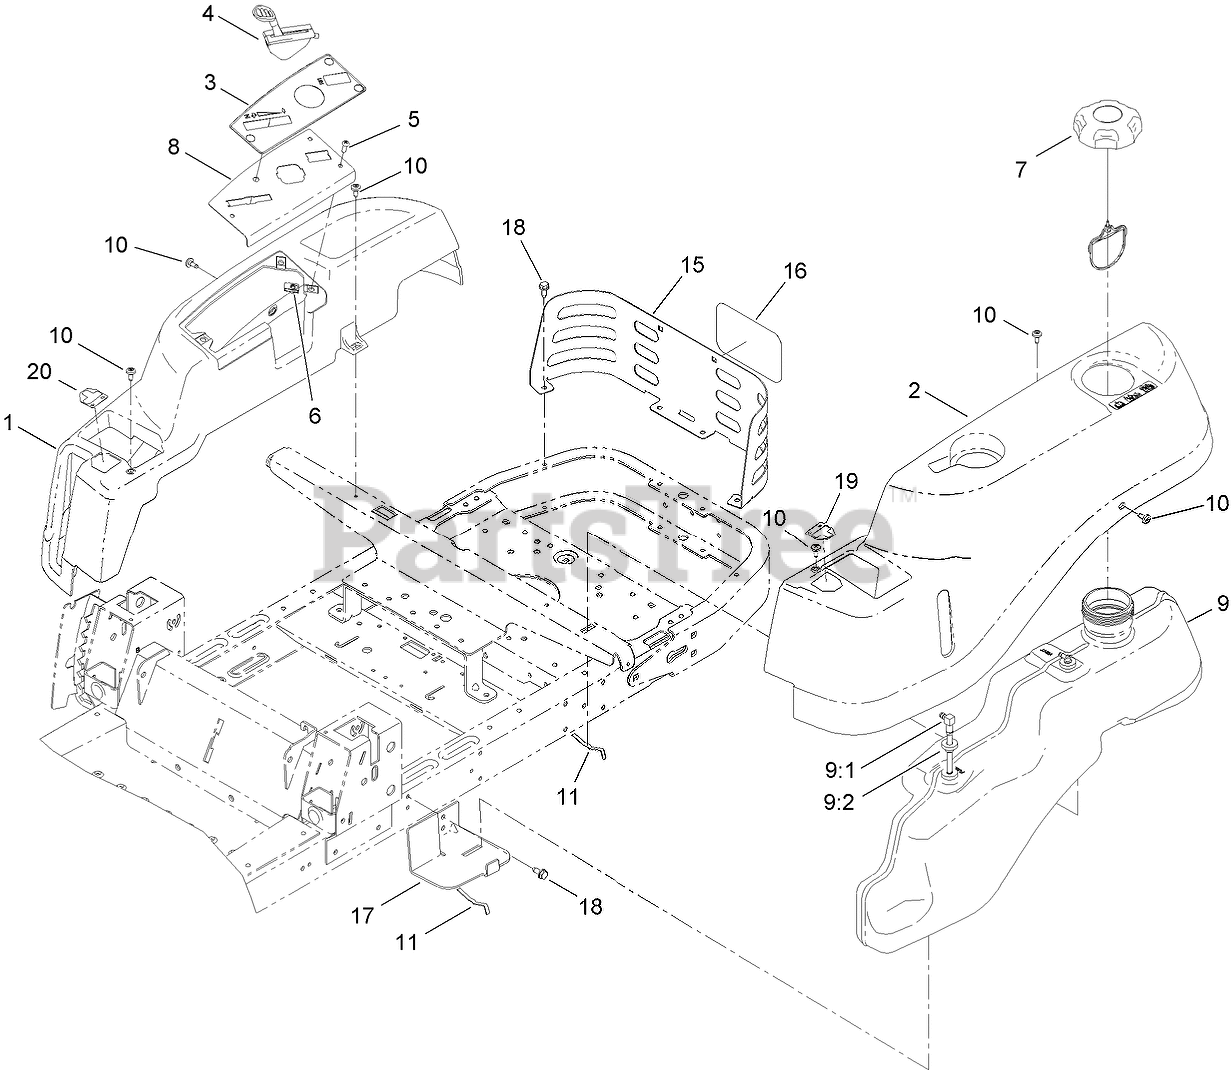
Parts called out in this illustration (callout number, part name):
1	POD-RH
2	POD-LH
3	DECAL-PANEL, CONTROL
4	CABLE-THROTTLE AND CHOKE
5	SCREW-PRH
7	CAP-FUEL, RATCHETING
8	PLATE-CONTROL
9	FUEL TANK ASM
9:1	CONNECTOR-ELBOW, 90 DEG
9:2	BUSHING
10	SCREW-SHOULDER
11	SPRING
15	GUARD-REAR
17	SUPPORT-TANK, FRONT
18	SCREW-HWHTF
19	DECAL-CONTROL LEVER, LH
20	DECAL-CONTROL LEVER, RH
